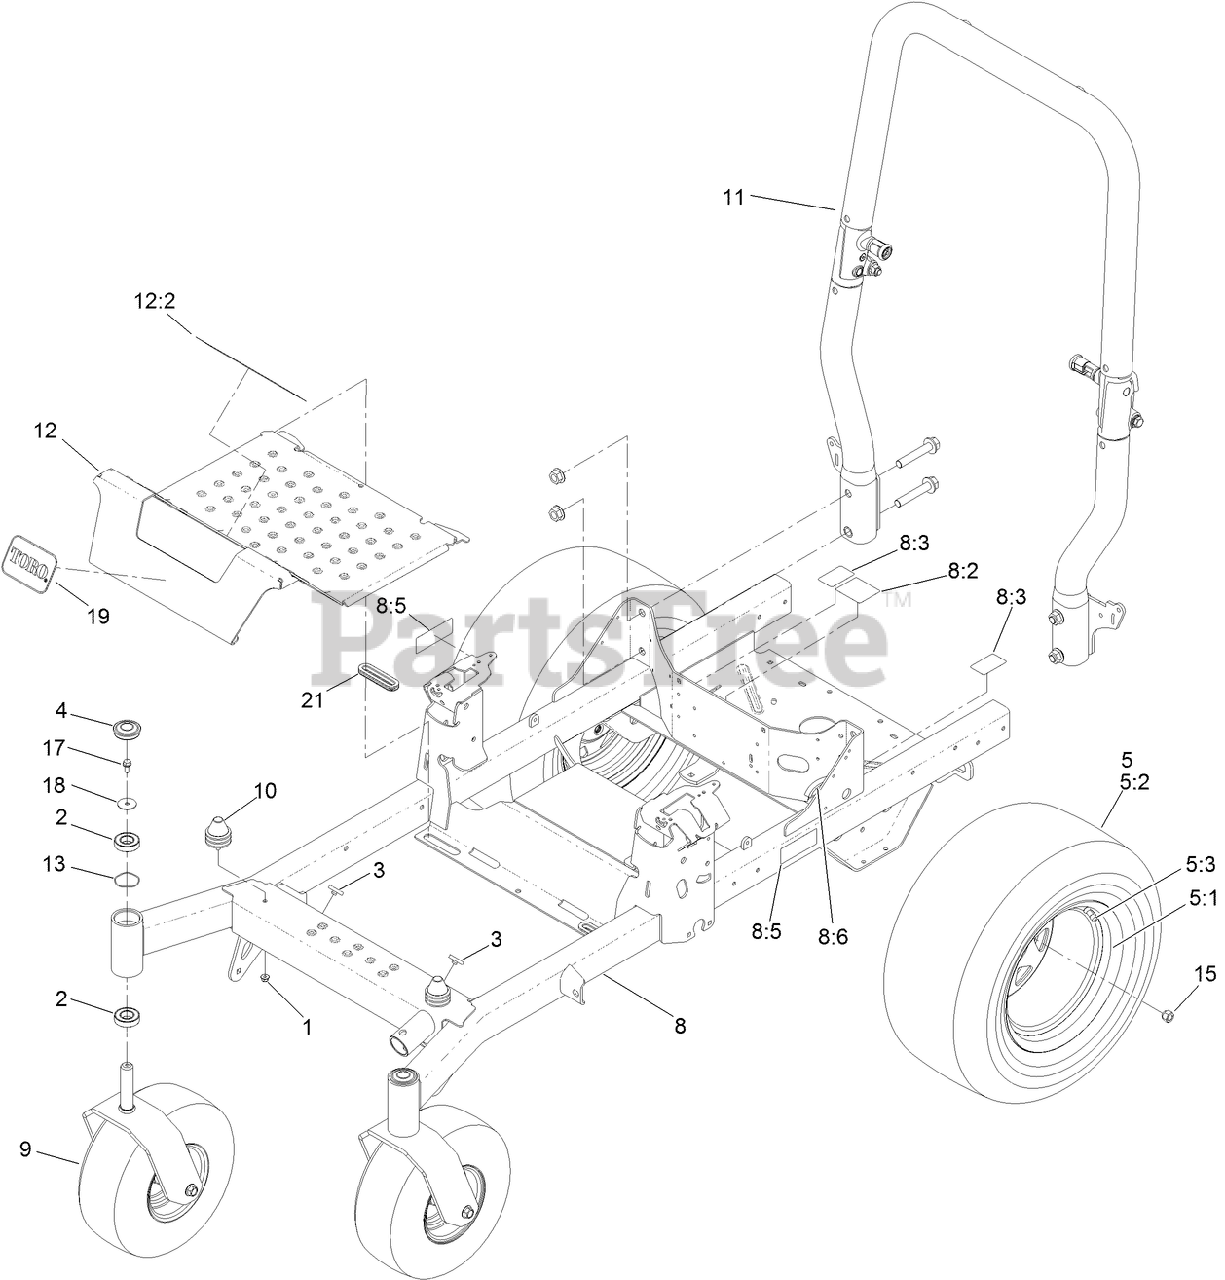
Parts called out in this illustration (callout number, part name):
1	NUT-HF, NI
2	BEARING-BALL
3	BUMPER-PUSH-IN, RUBBER
4	CAP-GREASE
5	WHEEL AND TIRE ASM
5:1	RIM-WHEEL
5:2	TIRE
5:3	STEM-VALVE
8	FRAME ASM
8:2	DECAL-ROUTING, BELT
8:3	DECAL-RELEASE, DRIVE
8:5	DECAL-WARNING
8:6	STRIP-SEAL
9	FRONT CASTER ASM (W/FORK)
10	ISOLATOR
11	ROPS ASM
12	PAN-FLOOR
12:2	DECAL-DANGER
13	SPRING
15	NUT-LUG
17	SCREW-HHF
18	WASHER-FLAT
19	DECAL
21	GROMMET-RUBBER
